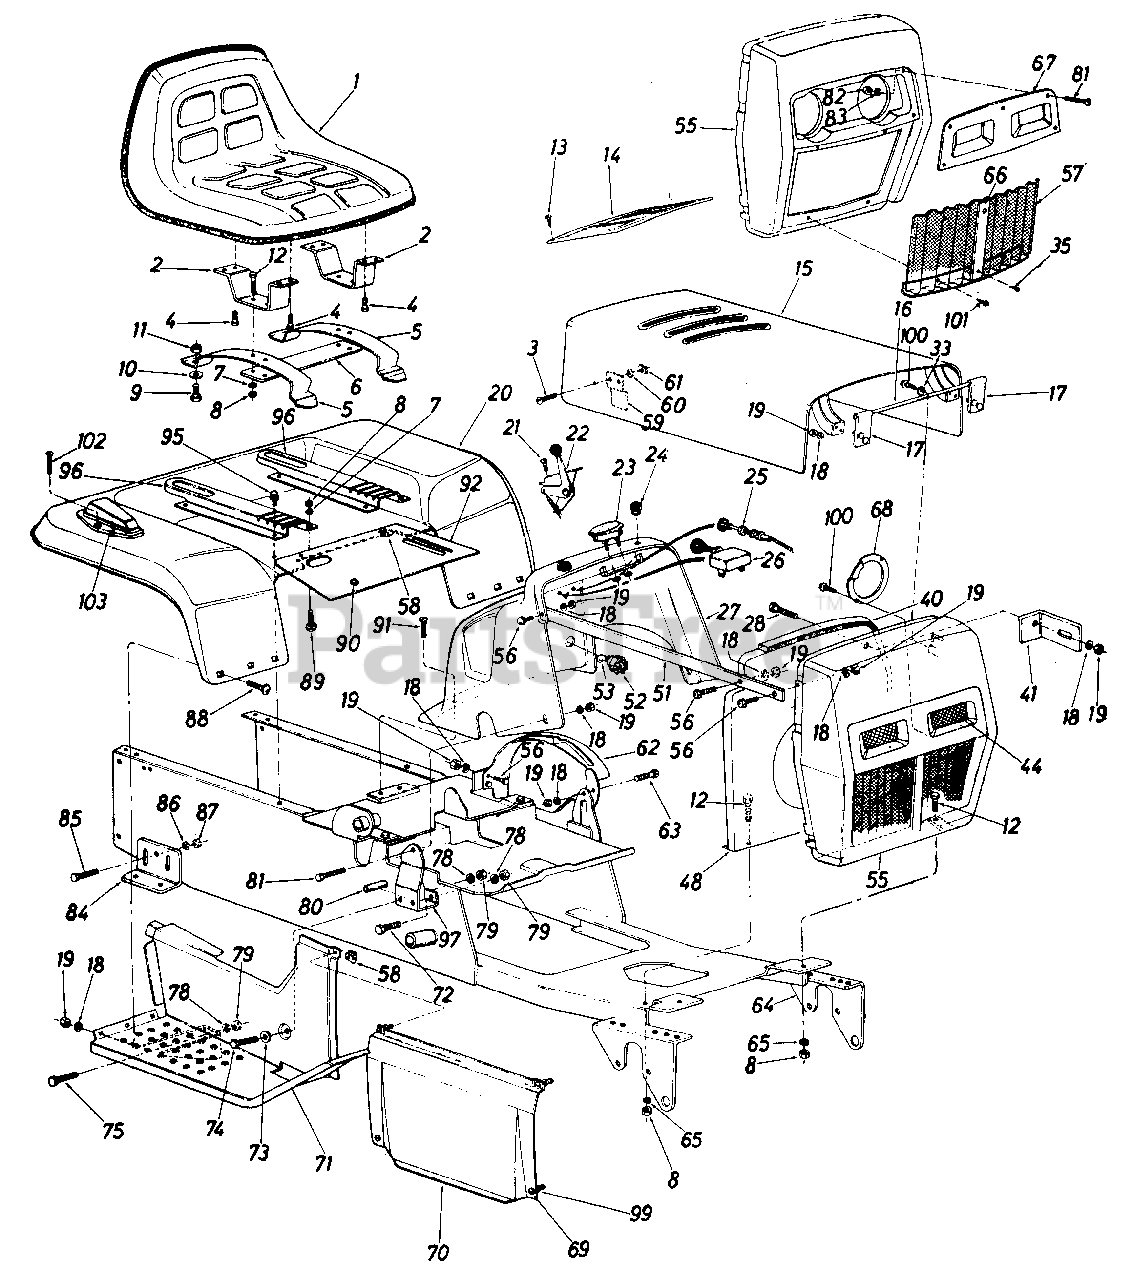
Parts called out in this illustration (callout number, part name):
1	Seat Ass'y. Comp.
2	Seat Support Brkt.
3	Truss Hd. Mach. Scr. #10-24 x.38" Lg.
4	Hex Wash. Hd. Self-Tap Scr. 3/8-16 x .75" Lg.
7	L-Wash. 5/16" Scr.
8	Hex Nut 5/16-18 Thd.
9	Nylon Scr 1/2-13 x .75" Lg.
10	Fl-Wash .531 I.D. x .930 O.D.
11	Hex Cent. L-Nut 1/2-13 Thd.
12	Hex Scr. 5/16-18 x .75" Lg.
13	Self-Tap Oval Hd. Scr. 1/2" Lg .
14	Dash Panel Cover
15	Hood Ass'y.
17	Hood Hinge Ass'y.
18	L-Wash. 1/4" Scr.
19	Hex Nut 1/4-20 Thd.
20	Rear Fender
21	Fl-Hd. Truss Scr. #10 x .62" Lg.
22	Throttle Control
23	Ammeter
24	Rubber Bumper
25	Choke Control
26	Light Switch
28	Hex Scr. 1/4-20 x .62" Lg.
33	Fl-Wash. .250 I.D. x 1.25 O.D.
41	Heat Shield Brkt.
44	Head Lamp
48	Heat Shield
51	Grille Strap
52	Ignition Switch
53	Ignition Key
55	Grille
56	Hex Scr. 1/4-20 x .75" Lg.
57	Grille Screen
58	Clip-On Receptacle
61	Hex Nut #10-24
62	Speed Control Guide
63	Truss Mach. Scr. 1/4-20 x .75" Lg.
64	Frame Ass'y.
65	Bell-Wash. 5116" Scr.*
66	Moulding
67	Headlight Bezel
68	Headlight Retainer
69	1/4-Turn Stud
70	Hood Lower Side Panel
71	Foot Step Panel Ass'y. R. H .
72	Hex Scr. 3/8-16 x 1.00" Lg. Grade 5
73	Fl-Wash. .385 I.D. x .62 O.D.
74	Hex Scr. 3/8-16 x 3.00" Lg.
75	Hex Scr. 3/8-16 x 1.00" Lg. Grade 5
78	L-Wash. 3/8" Scr.
79	Hex Nut 3/8-16 Thd.*
80	Spacer .375 I.D. x .62 O.D. x 2.00" Lg.
81	Truss Mach. Scr. #10-24 x 1.0" Lg.
82	Sq. Nut #10-24 Thd.
83	Ext. L-Wash. #10 I.D.
84	Transaxle Support Brkt.
85	Rd. Hd. Rib Neck Scr. 318-24
86	L-Wash. 3/8" Scr.
87	Hex Nut 3/8-24 Thd.
88	Carr. Bolt 1/4-20 x .50" Lg.
89	Carr. Bolt 5/16-18 x .62" Lg.
90	Snap Bushing
91	Fl-Hd. Self-Tap Scr. 1/4-20 x .62" Lg.
96	Seat Adjustment Brkt.
100	Thread Rolling Scr. 1/4"
101	Drive Scr. #7
102	Fl. C-Sunk AB-Tap Scr. #10 x 1.0" Lg.
103	Taillight
